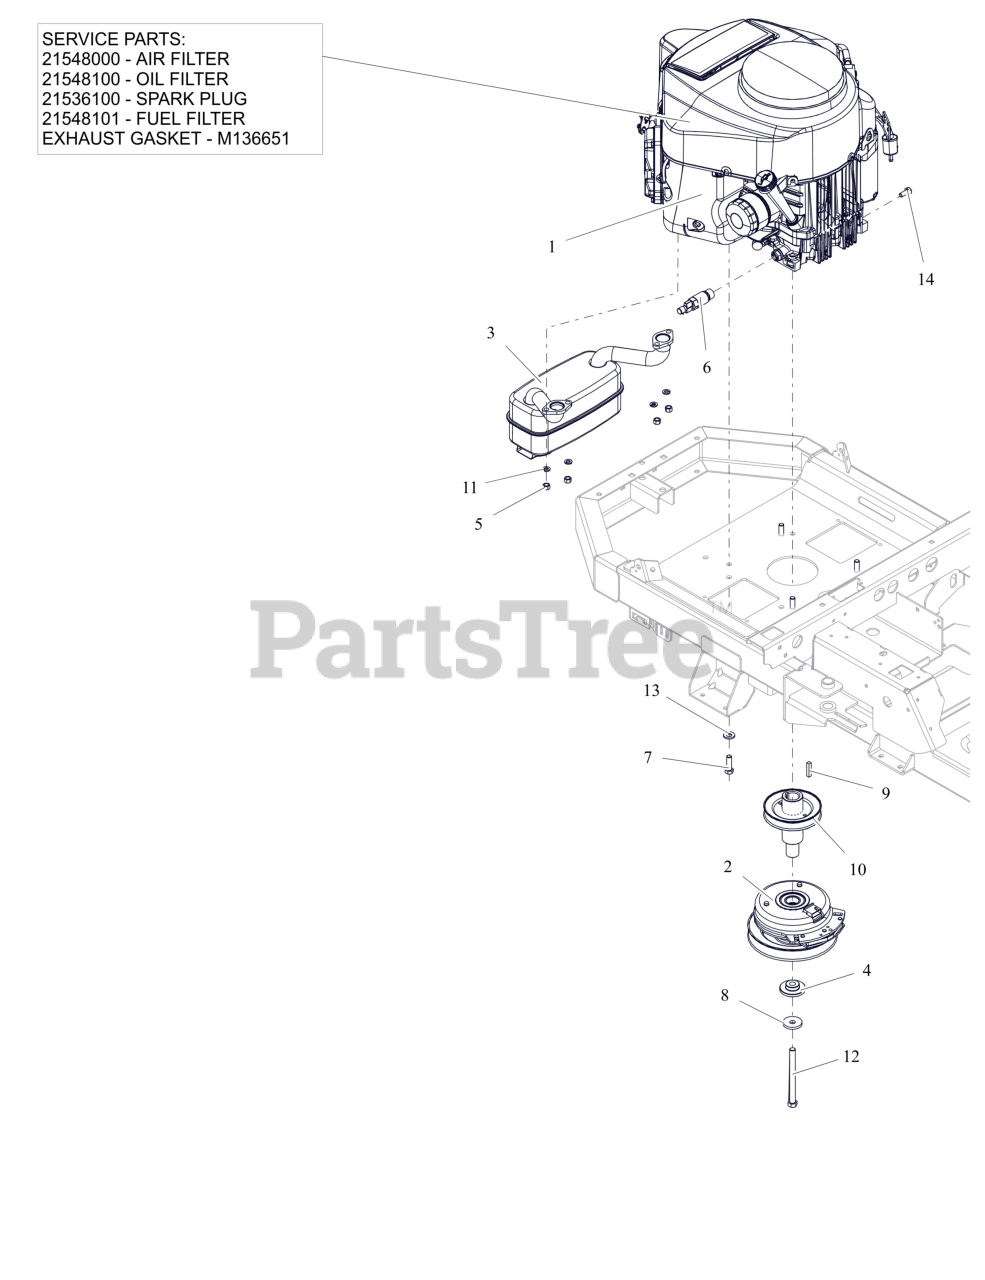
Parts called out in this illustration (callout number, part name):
1	ENGINE, KAWASAKI FR691 23HP
1	AIR FILTER, KAWASAKI FR
1	OIL FILTER, KAWASAKI FR
1	PLUG, SPARK
1	FUEL FILTER-KAWASAKI FR
1	GASKET, MUFFLER #
2	CLUTCH,105FTLB MONOPOLE 6.83"
3	MUFFLER - KAWASAKI
4	BSHG-FLG .469X1.06X.574X2.0
5	NUT, HEX M8-1.25 G8.8 ZCC
6	DRAIN, OIL M20X2.5
7	BLT, HEX .38-16X1.25 G5 ZCC NT
8	WASHER, 7/16" SPRING DISK
9	KEY-SQ .25 X 1.25 X .25 SAE
10	WLDMT, DRIVE SHEAVE (LONG)
11	WSHR,LK-REG .312X.078 ZCC
12	BLT, HEX .44-20X5.00 G8 ZCC NT
13	WASHER, 3/8" SPRING DISC
14	BLT, HEX M8-1.25X20 G8.8 ZCC
